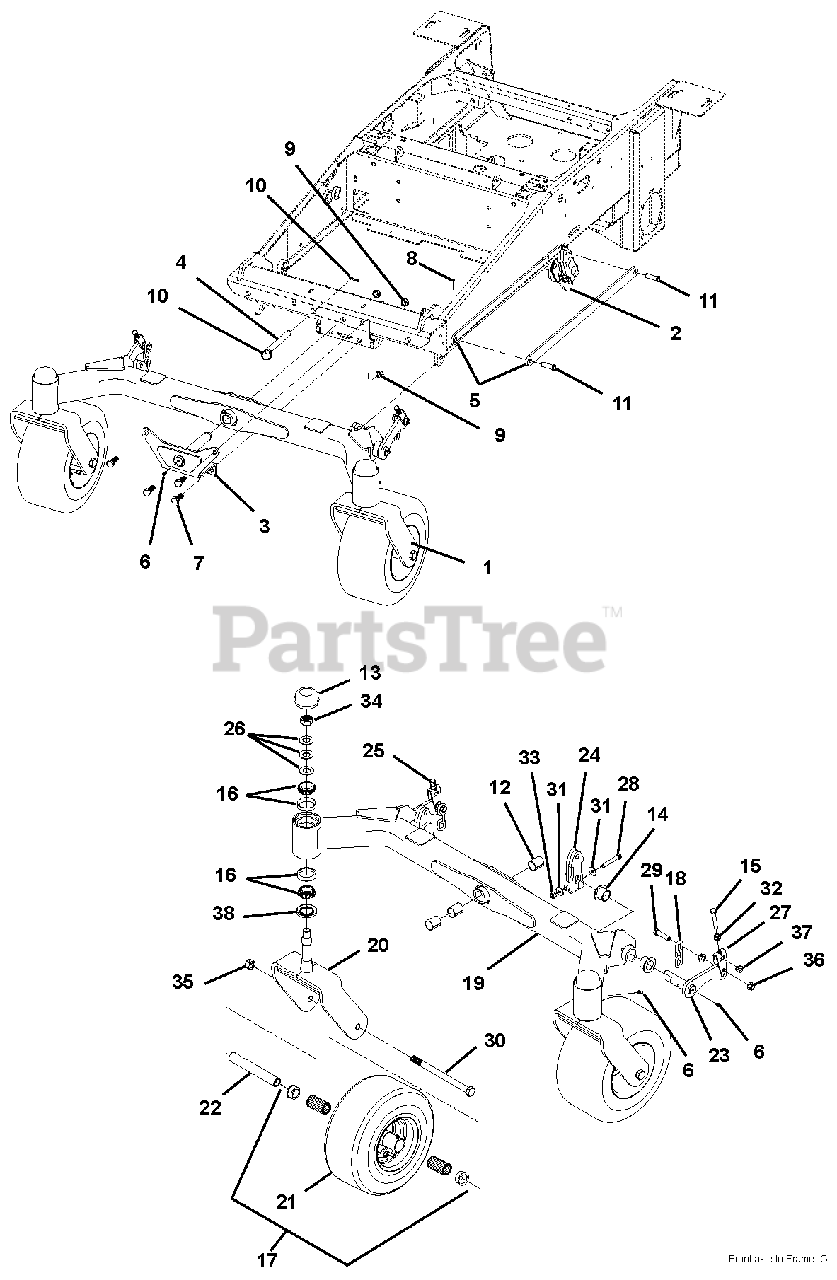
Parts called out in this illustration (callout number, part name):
1	Front Axle Frame Assembly (see view at bottom of p. 16 or see p. 14 for individual components)
2	Rear Lift Rod Assembly
3	Front Axle Bracket
4	Pin, MFG .625 x 5.00 x 4.38
5	Connector Link
6	Fitting, 1/4-28 Straight Grease Zerk
7	Bolt, 1/2-13 x 1.25 Hex 5
8	Ring, Rue .500 x .062 x 1.42
9	Nut, Locking, Cone
10	Ring, Wire - .080 x 1.25
11	Pin, CVS .500 x 1.50 x 1.27
12	Bearing, Sleeve 1.00 x 1.13 x 1.25
14	Bearing, Flange 1.00 x 1.25 x .944
15	Bolt, 3/8-16 x 2.25 HEX 5
16	Bearing Assembly, 1 in. Diameter Spindle
17	Kit, Bearings and Caps 1.00" (does not include tire and rim)
18	Chain - 3 Links
19	Front Axle Weldment
20	Weldment, Z Front Wheel Fork
21	Assembly, Tire & Rim - 13/6.50 x 6 Smooth (includes item 17)
22	Tube, Front Tire Axle
23	Weldment, LH Front Pivot
24	Weldment, Front Pivot Clamp
25	Assembly, Front Pivot (Includes items 15, 27, 32 and 37)
26	Washer, .750 x 1.50 x .072 BLVL
27	Link, U-Bracket
28	Bolt, 3/8-16 x 2.25 Hex 5
29	Bolt, Hex 7/16-14 x 2.00 Hex SPC
30	Bolt, 5/8-11 x 8.50 Hex 5
31	Washer, Flat, Steel .438 x 1.00 x .083
32	Locknut, 3/8-16 Whiz
33	Nut, Locking, Flange .375-16
34	Locknut, 3/4-16 Crown
35	Nut, Locking, Center .62-11
36	Locknut, 7/16-14 Whiz
37	Nut, 3/8-16 Square
38	Seal, 1.00 Roller Bearing
